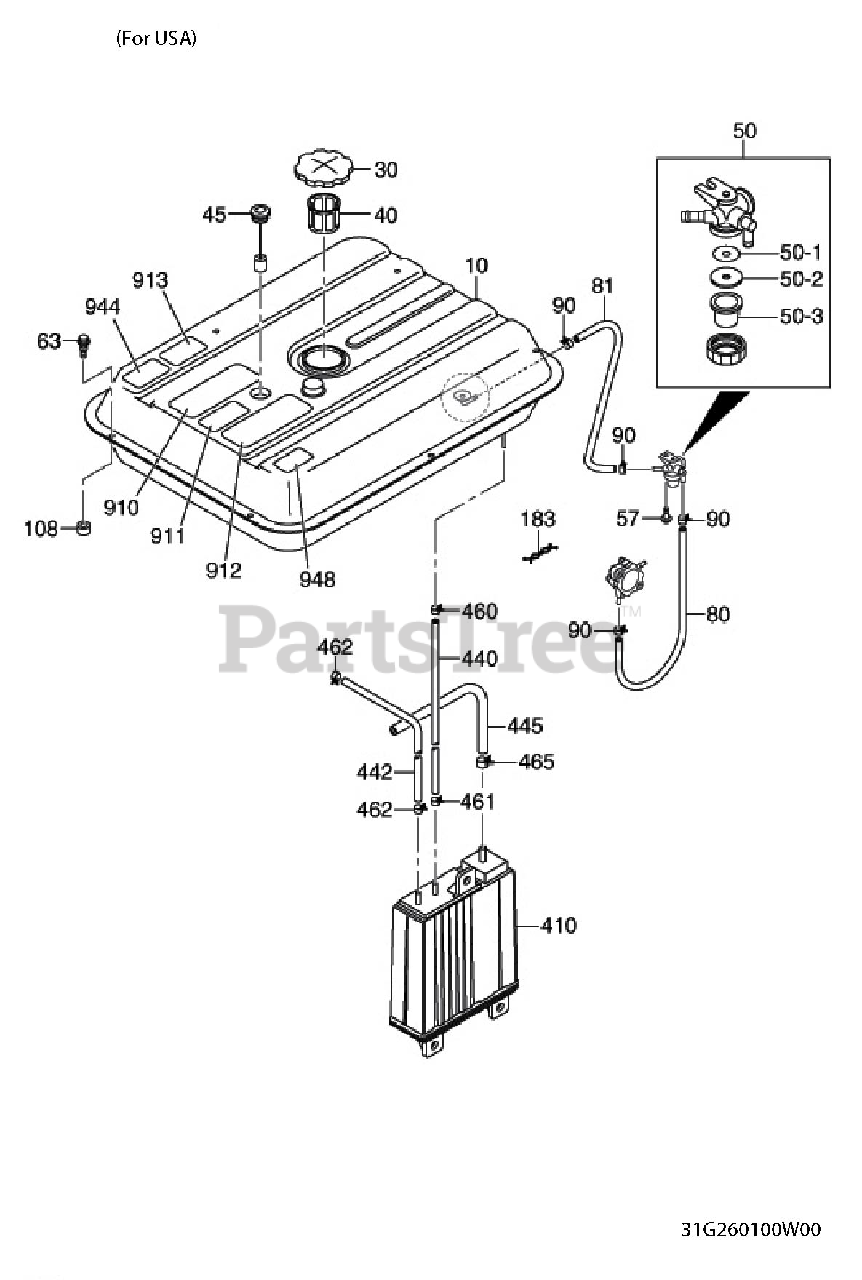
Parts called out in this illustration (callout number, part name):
10	FUEL TANK ASSY
30	FUEL TANK CAP AY
40	FUEL FILTER
50	FUEL STRAINER ASSY
80	RUBBER PIPE
81	RUBBER PIPE
90	HOSE CLAMP
410	CANISTER AY
440	RUBBER PIPE
442	RUBBER PIPE
460	HOSE CLAMP
461	HOSE CLAMP
462	HOSE CLAMP
465	HOSE CLAMP
910	LABEL (warning)
911	LABEL (CO GAS)
912	LABEL (caution)
913	LABEL (WARNING)
944	LABEL(LEVEL CAUTION)
948	LABEL (SYMBOL-TANK)
